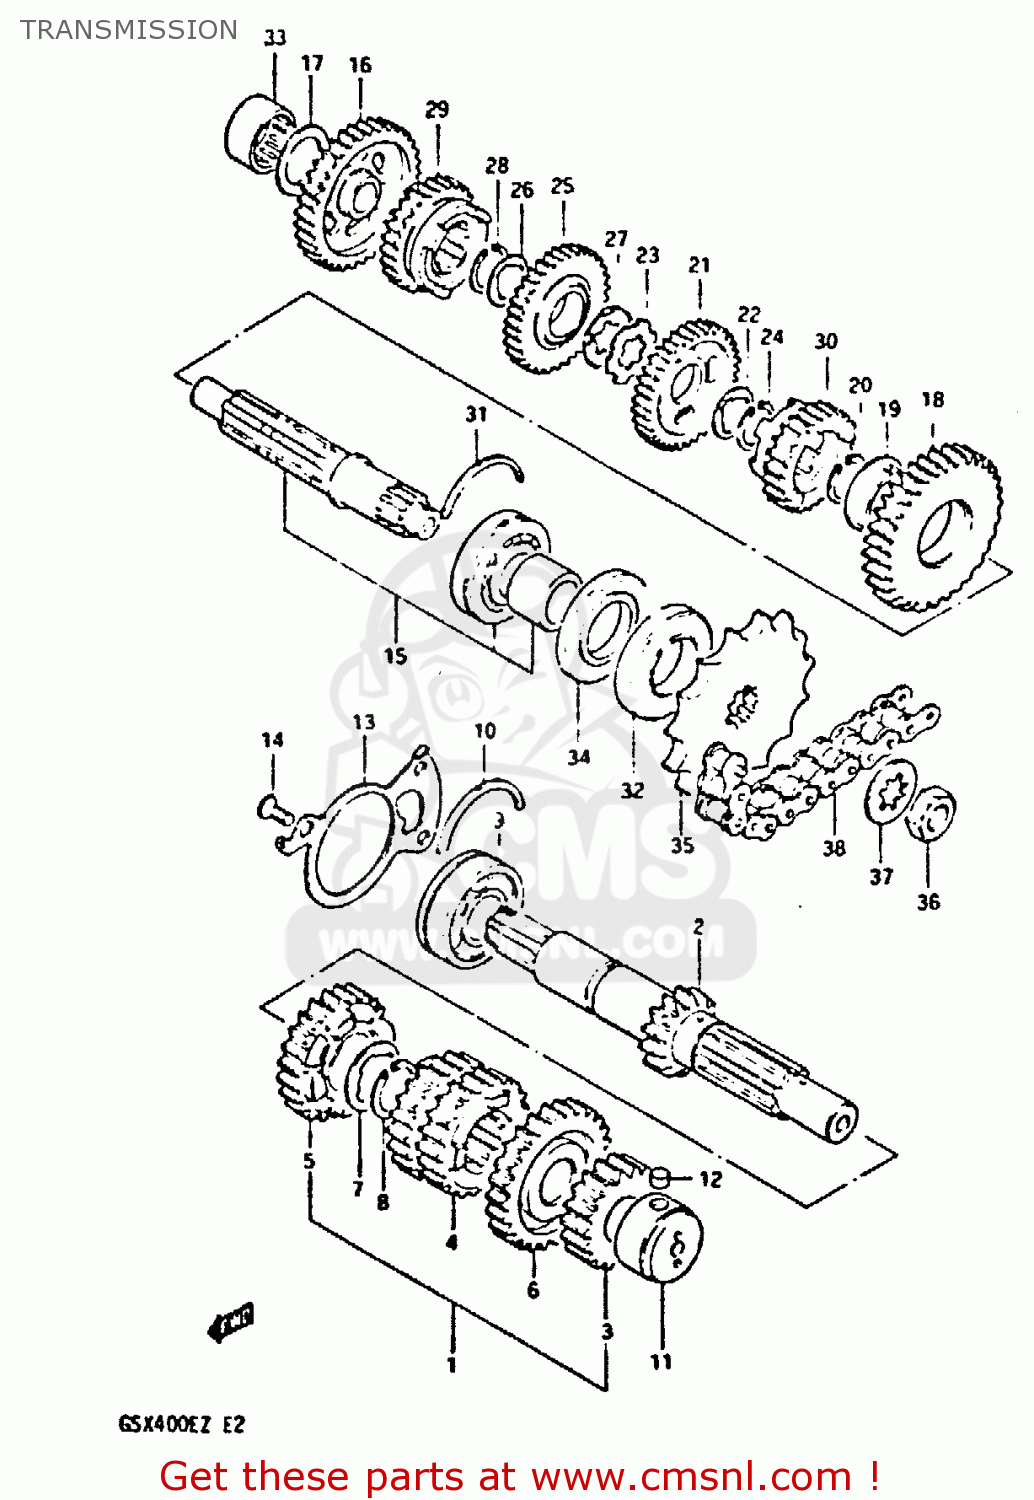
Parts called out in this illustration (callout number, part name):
1	SHAFT,COUNTER
2	SHAFT,COUNTER
3	GEAR,2ND DRIVE(NT:18)
4	GEAR,THIRD DRIVE
5	GEAR,FIFTH DRIVE
6	GEAR,SIXTH DRIVE
7	WASHER
8	CIRCLIP
9	BEARING(25X62X17)
10	C-RING
11	ROLLER BEARING (20X34X2
12	PIN
13	PLATE,COUNTERSHAFT BEARING
14	SCREW
15	SHAFT,DRIVE
16	GEAR,FIRST DRIVEN
17	WASHER
18	GEAR,SECOND DRIVEN
19	BUSHING
20	CIRCLIP
21	GEAR,THIRD DRIVEN
22	WASHER,LOCK
23	WASHER,LOCK
24	CIRCLIP
25	GEAR,FOURTH DRIVEN
26	WASHER,LOCK
27	WASHER
28	CIRCLIP
29	GEAR,5TH DRIVEN(NT:25)
30	GEAR,SIXTH DRIVEN
31	C-RING
32	SEAL,OIL(32X62X7)
33	ROLLER BEARING (20X34X1
34	SEAL,OIL(32X62X5.5)
35	SPROCKET,ENGINE(NT:16)
36	NUT
37	WASHER
38	CHAIN ASSEMBLY,DRIVE
